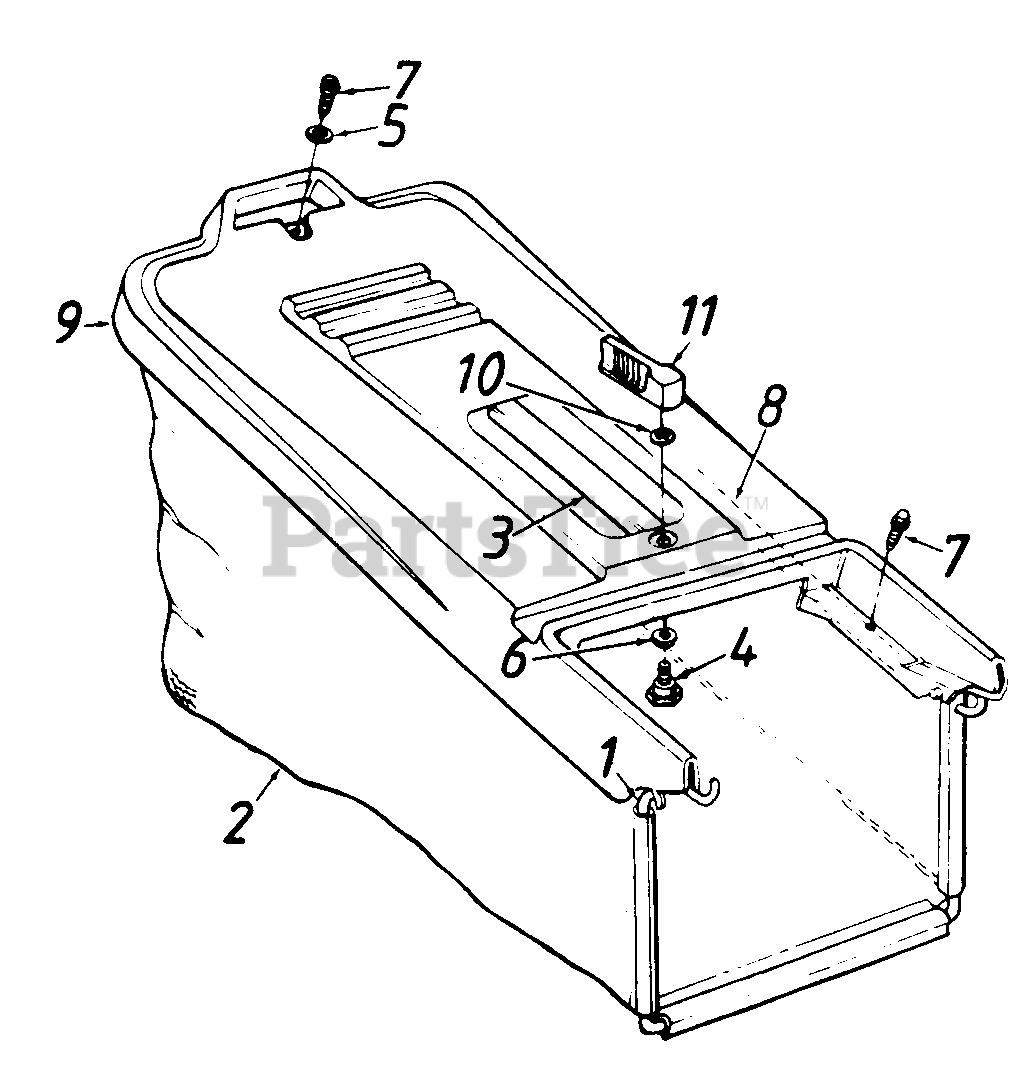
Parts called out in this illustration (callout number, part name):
1	Front Catcher Frame
2	Grass Bag
3	Hardtop Handle
4	Shoulder Bolt
5	Fl-Wash. .281 I.D.
6	Bowed Washer
7	Hex AB-Tap Scr. 1/4 x .62" Lg.
10	Internal L-Wash. 1/4" I.D.
11	Locking Knob
